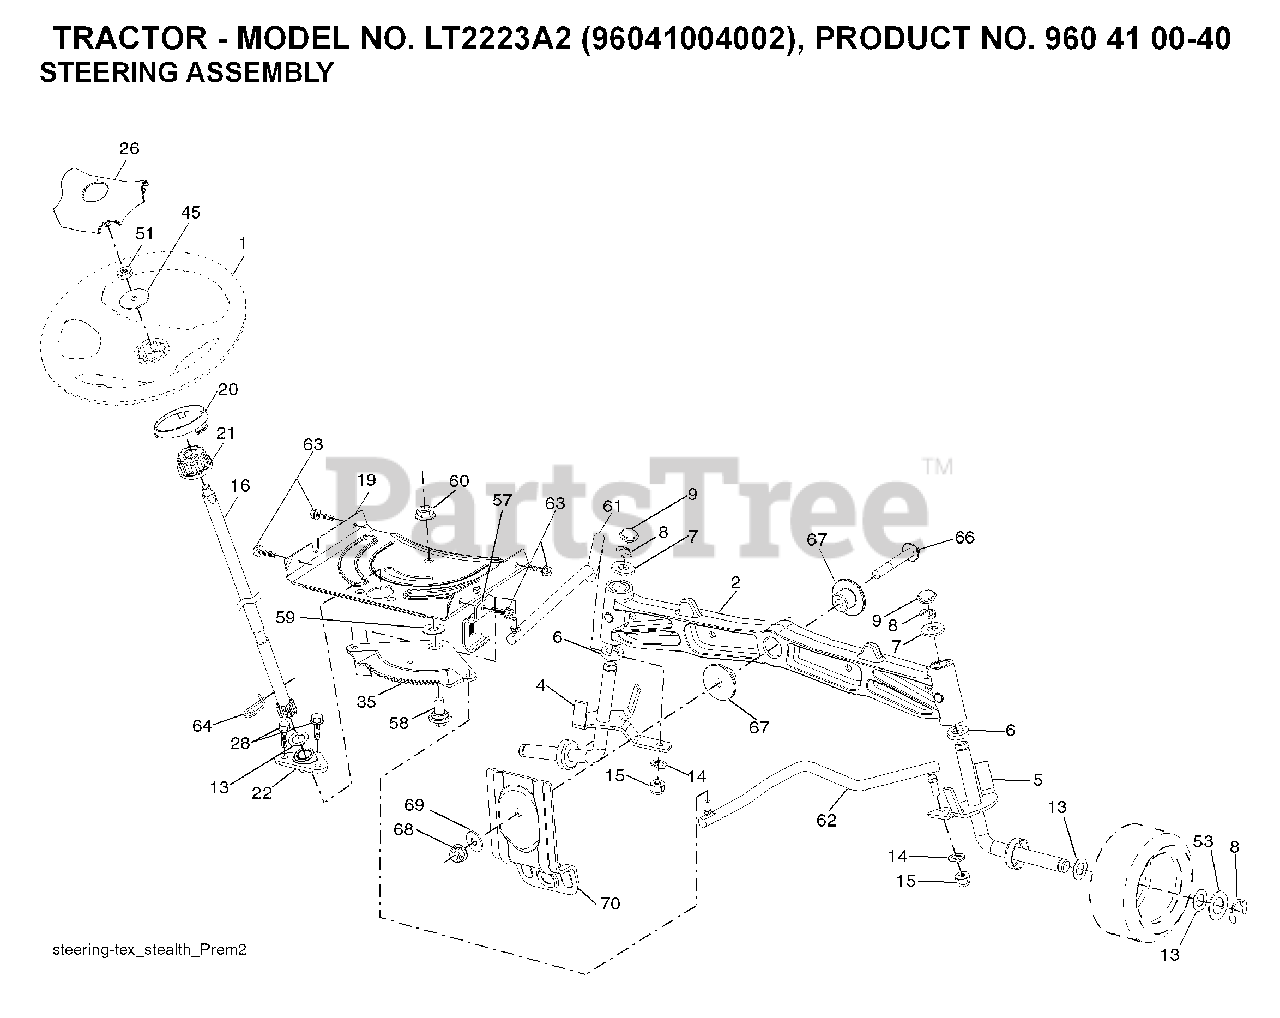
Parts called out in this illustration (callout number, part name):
1	WHEEL.STEERING.PREM.2.BLK
2	AXLE.CAST.IRON
4	SPINDLE.WELDED.LH.16"TEX
5	SPINDLE.WELDED.RH.16"TEX
8	RING CLIP
9	CAP.SPINDLE
14	WASHER, LOCK 3/8
15	NUT CROWNLOCK 3/8-24
16	SHAFT.STEER.STEALTH.DD
19	PLATE.STEER.DDL.NLT/NG
20	BOOT.STEERING.
21	ADAPTER, WHEEL STNG..
22	BUSHING.ASM.STEERING.A
26	INSERT.CAP.STRG.WH.BLACK
28	SCREW, 3/8-16X3/4
35	GEAR.SECTOR.PLATE.DDL.
45	WASHER.11/32
51	NUT.HEX.1/2-20
53	WASHER.HARDENED
57	BRKT.UPSTOP.GT/LT.TEX
58	BOLT.SHOULDER.SECTOR.P
59	WASHER.THURST.SECTOR.S
60	NUT FLANGE LOCK 5/8-11
61	DRAGLINK.LH.BALLSTUD.D
62	DRAGLINK.RH.BALLSTUD.D
63	SCREW
64	RETAINER.CLIP.SPRING.S
66	BOLT HEX FGHD 7/16-14 X 3 SERR
67	BUSHING.PM.FRONT AXLE
68	NUT.LOCK.FLANGE.7/16
69	WASHER.1.5X.505X.118
70	BRKT.DECK.SUSPENSION.F
118	BUSHING, AXLE CAST
